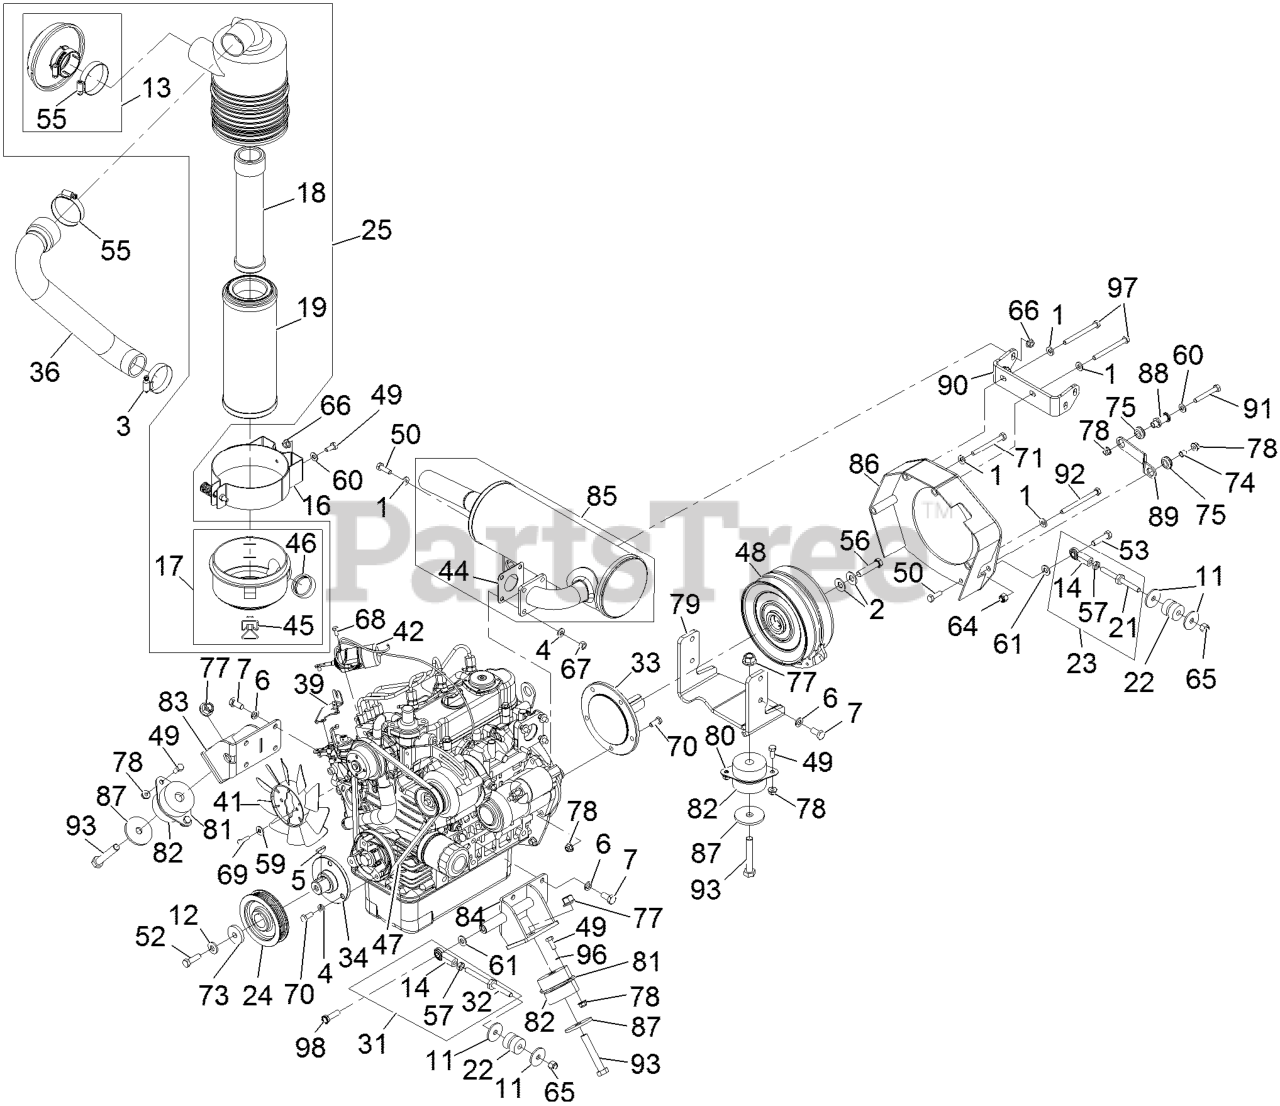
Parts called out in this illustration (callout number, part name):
1	WASHER-SPRING
2	WASHER-SPRING
3	CLAMP-HOSE
4	WASHER-LOCK
5	KEY-WOODRUFF
6	Washer-Lock M10
7	SCREW-CAP
12	WASHER-BELLEVILLE
13	HOOD-CLEANER, 2" AIR INTA
14	JOINT-BALL, END
16	BRACKET-FILTER, AIR
17	COVER-FILTER, AIR
18	FILTER-AIR, SAFETY
19	FILTER-AIR
21	LINK,REAR A-T AXIAL
22	ISOLATOR-LINK
23	BALL JOINT LINK ASM
24	SHEAVE,5K 4"PD POLY-V
25	FILTER-AIR
31	ASM, A-T LINK
32	LINK,REAR A-T AXIAL
33	SHAFT,KUBOTA 902 STUB
34	HUB,PUMP DRIVE
36	HOSE,AIR INTAKE D902(8015
39	BRACKET-SUPPORT, THROTTLE
41	FAN,COOLING 7"
42	SOLENOID,FUEL
44	GASKET-MUFFLER
45	CLIP-CLEANER, AIR
46	EJECTOR, NELSON AIR CLEAN
47	BELT,KUBOTA 902 ALT
49	SCREW-HH
50	SCREW-HH
52	SCREW-HH
53	SCREW-HH
55	CLAMP-HOSE
56	SCREW-HH
57	NUT-HJ
59	WASHER-FLAT
60	WASHER-PLAIN
61	WASHER-FLAT
64	NUT-LOCK, NI
65	NUT-LOCK
67	NUT-HEX
68	SCREW-HH
69	SCREW-HH
70	SCREW-HH
71	SCREW-HH
73	WASHER-CLUTCH
75	GROMMET
77	Nut-Lock 1/2-13
78	NUT-HF, NI
79	BRACKET,ENGINE MOUNT
80	FLANGE ASM
81	FLANGE-11GA
82	ISOLATOR,ENGINE
83	ENGINE MOUNT-RH
84	ENGINE MOUNT-LH
85	MUFFLER KIT - KUBOTA
86	WLD,FLYWHEEL COVER
88	CLUTCH STANDOFF
89	CLUTCH LINK
90	SUPPORT-MUFFLER
91	SCREW-HH
92	SCREW-HH
93	SCREW-HH
96	WASHER-LOCK
97	SCREW-HH
98	SCREW-HH, LOCK
